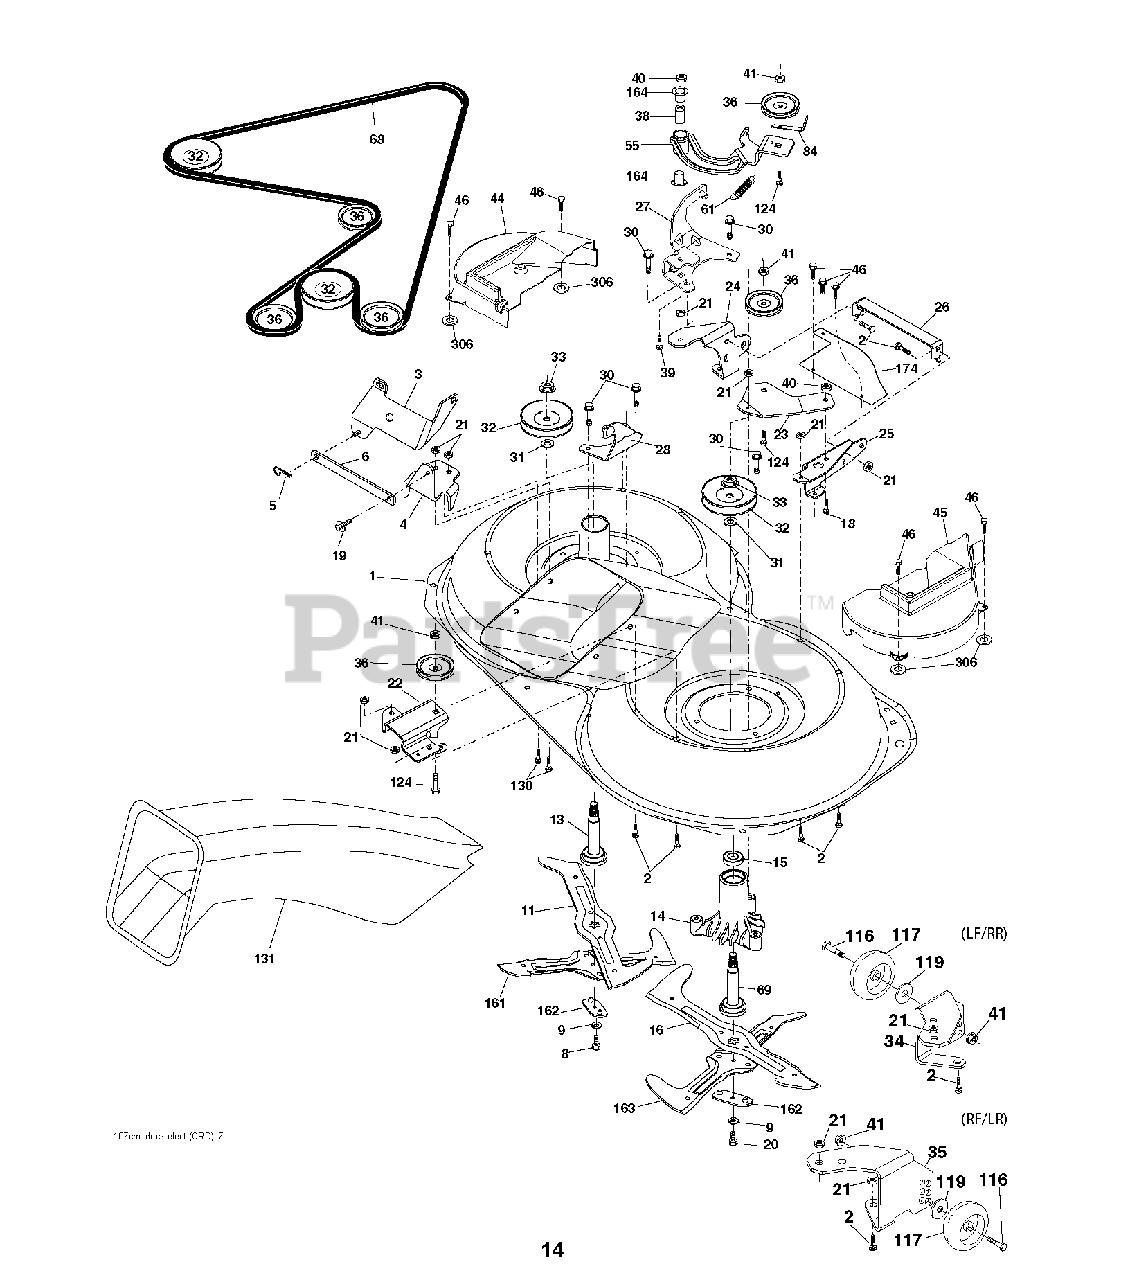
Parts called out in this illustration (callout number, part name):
2	BOLT
3	BRACKET.ASM.BAR.SWAY.CHASS
5	RETAINER-SPRNG RB
6	BAR SWAY
9	LOCKWASHER
11	BLADE.3N1.LH.CRD
13	SHAFT ASM VENT
14	HSG MANDREL
16	BLADE.3N1.RH.CRD
18	BOLT
19	BOLT SHD 5/16-18
21	LOCKNUT
22	BRACKET
23	BRACKET
27	BRACKET
30	SCREW, WASHER HEAD
31	WASHER.SPACER.MANDREL
33	NUT.FLANGE.LOCK.TOP
36	PULLEY.IDLER.4.25
40	LOCKNUT
41	NUT LOCK FLG 3/8-16 UNC
46	SCREW.1/4-20X5/8
55	ARM IDLER
68	HEX-BELT 107 MOWER
69	SHAFT.ASM.W/LWR.BRG.RH.THREAD
84	KEEPER, BELT IDLER
116	BOLT.SHOULDER.3/8-16X3-5/8
117	WHEEL. GUAGE RALLY
124	BOLT.3/8-16X1.50
131	CHUTE BAGGER
164	BRNG T
306	PALNUT 1/4
